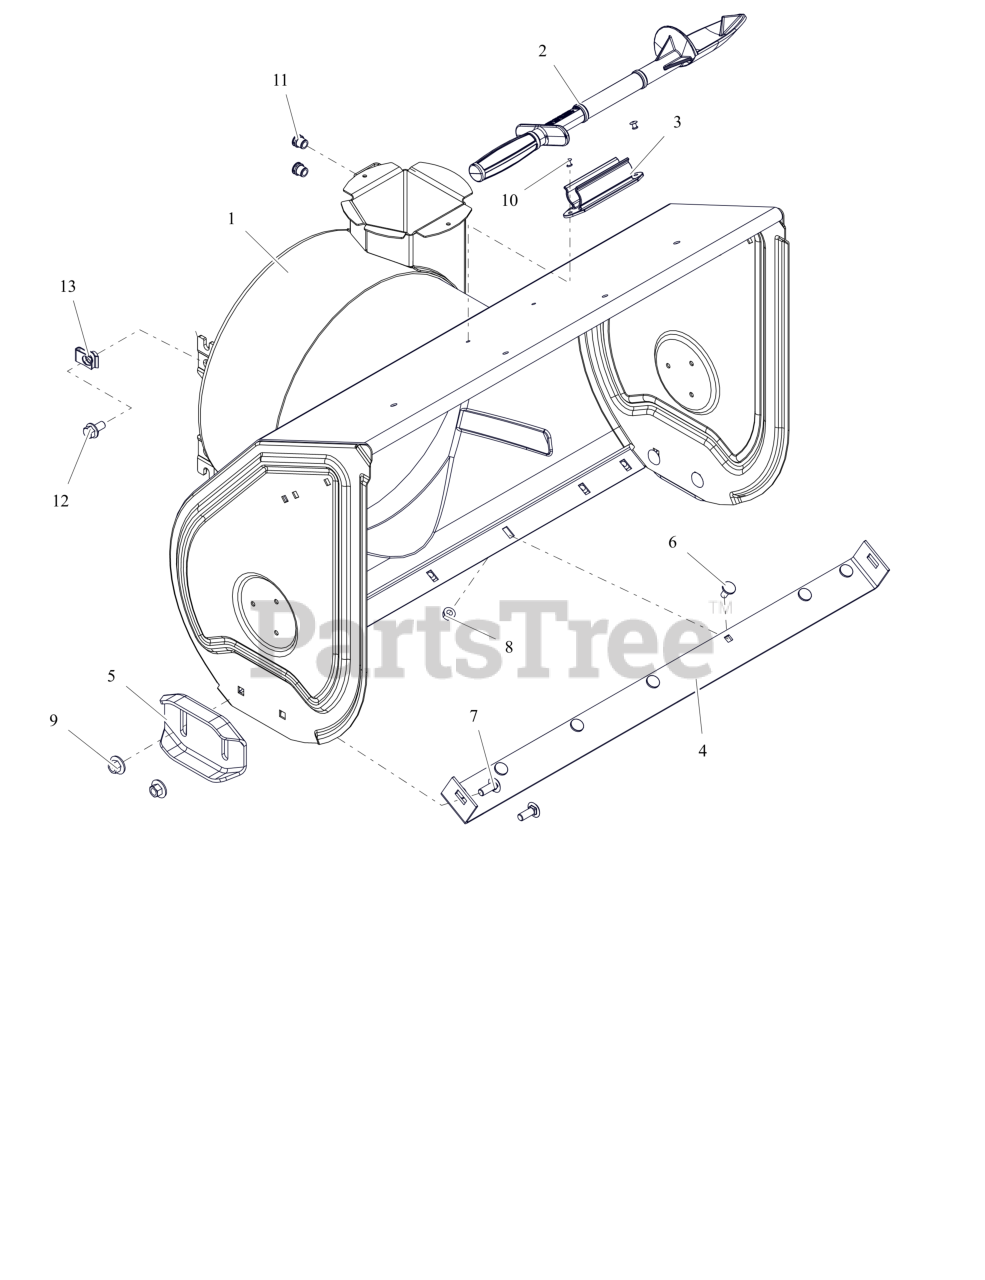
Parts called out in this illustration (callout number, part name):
1	HOUSING, BLOWER W/SAFETY DECAL 30"
2	DEVICE, SNOW CLEAN OUT
3	MOUNT, SNOW CLEAN OUT
4	BLADE, SCRAPER-30"
5	SKID SHOE, REVERSIBLE - ORANGE
6	BOLT, MODIFIED HEAD CARRIAGE
7	BLT,RHSSN .38-16X1.00 G5 ZCC
8	NUT-LK-TOP-FLG .312-18 GF ZCC
9	NUT- CON-LN .375-16 ZC120
10	RVT, POP .1875 ZCC
11	NUT,THD,INSERT .38-16 ZC120
13	NUT-RTNR .375-16X.37
